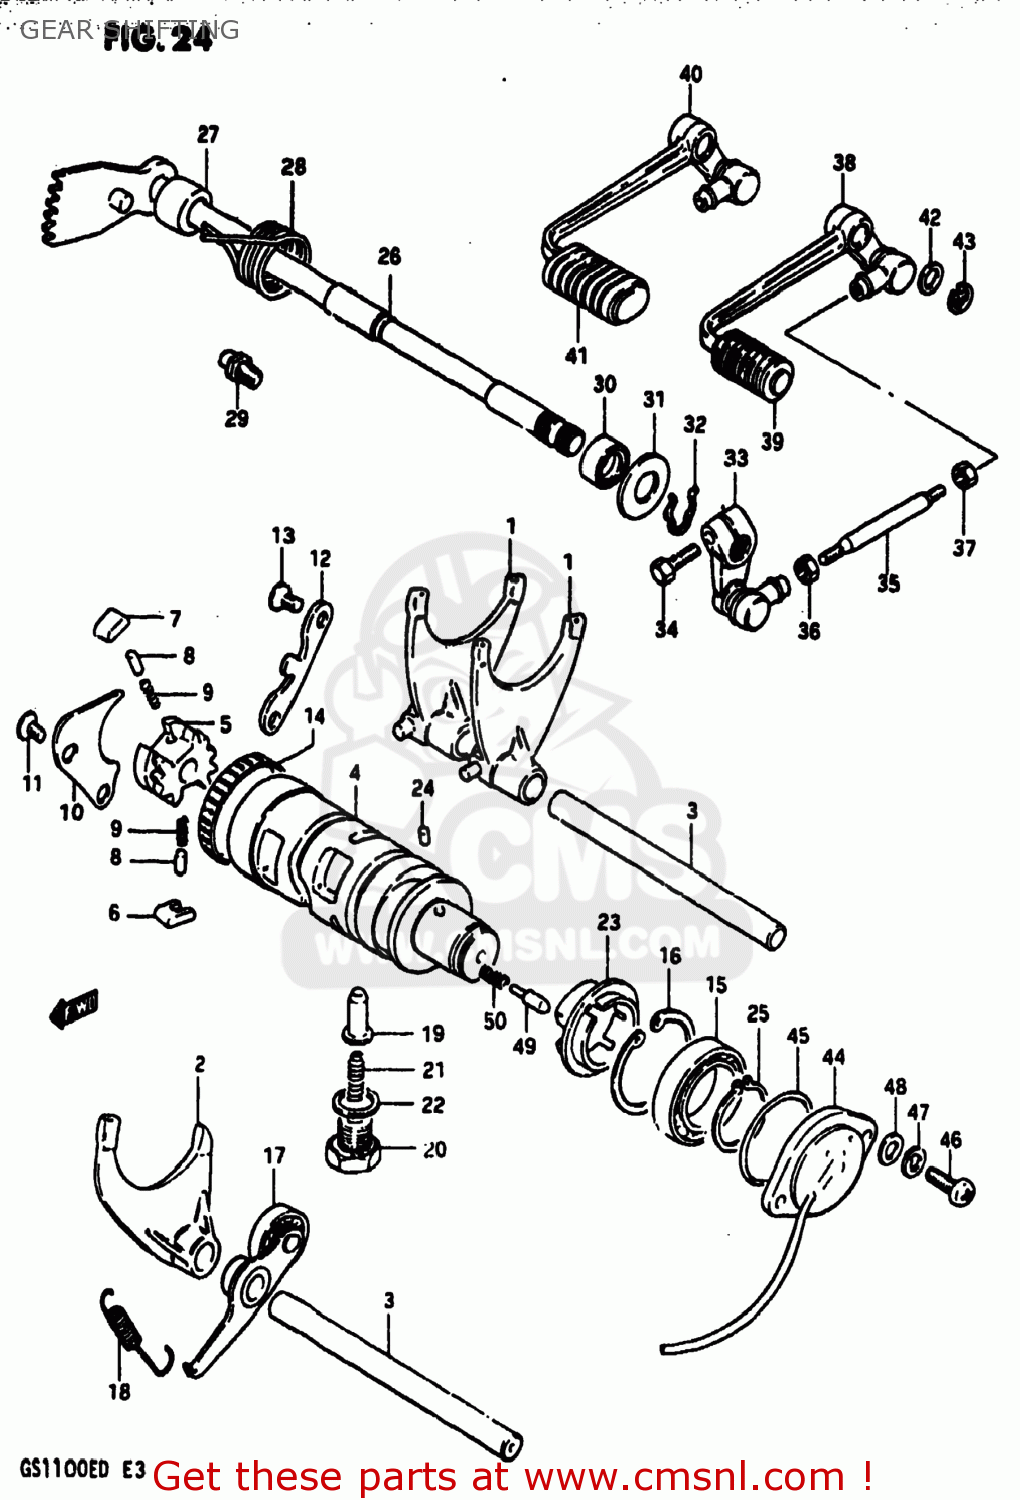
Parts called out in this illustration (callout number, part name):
1	FORK,GEAR SHIFT NO.1
2	FORK,GEAR SHIFT NO.2
3	SHAFT,GEAR SHIFT FORK
4	CAM,GEAR SHIFT
5	RETAINER,GEAR SHIFT CAM
6	PAWL,GEAR SHIFT NO.1
7	PAWL,GEAR SHIFT NO.2
8	PIN(5X8)
9	SPRING
10	LIFTER,GEAR SHIFT PAWL
11	SCREW
12	GUIDE,GEAR SHIFT CAM
13	SCREW
14	BEARING(43X49X12)
15	BALL BEARING
16	CIRCLIP,42MM
17	STOPPER,GEAR SHIFTING
18	SPRING
19	STOPPER,GEAR SHIFT CAM NO.2
20	HOLDER,GEAR SHIFT CAM STOP SPR
21	SPRING
22	GASKET(14X19.2X2) (NAS)
23	PLATE,GEAR SHIFT CAM STOPPER
24	PIN 4X6
25	CIRCLIP,25MM
26	SHAFT,GEAR SHIFT
27	SPACER(12X20X15.3)
28	SPRING
29	STOPPER,GEAR SHIFT CAM
30	OIL SEAL
31	WASHER (12.5X27X1.6)
32	SPRING,RETAINER
33	ARM,GEAR SHIFT LINK
34	BOLT
35	ROD,GEAR SHIFT LINK
36	NUT
37	NUT
38	LEVER ASSEMBLY,GEAR SHIFTING
39	RUBBER,GEAR SHIFT PEDAL
40	LEVER ASSEMBLY,GEAR SHIFTING
41	RUBBER,PEDAL
42	WASHER(12.5X20X1)
43	CIRCLIP
44	BASE ASSEMBLY,NEUTRAL SWITCH TERMINAL
45	O RING(D:2.4,ID:36.5)
46	SCREW
47	LOCK WASHER
48	WASHER
49	PIN(5X15.5)
50	SPRING
